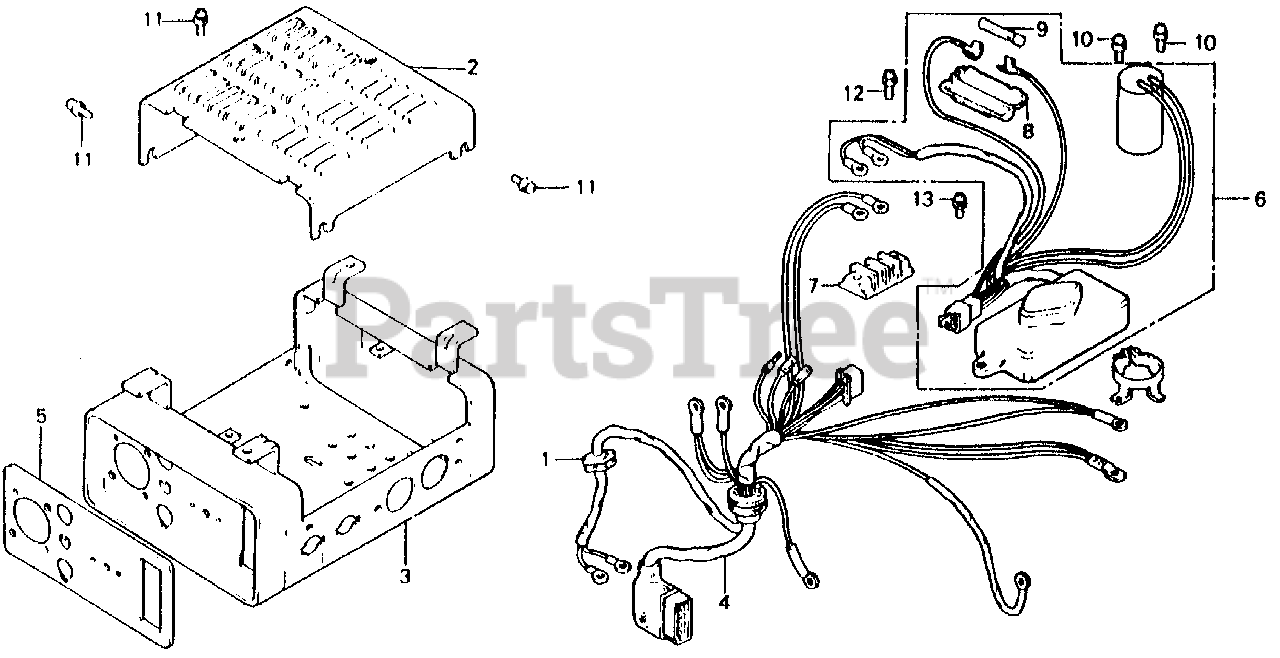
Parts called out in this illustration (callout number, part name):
1	BUSH, RUBBER
2	COVER, CONTROL BOX (UPPER) *R8* (BRIGHT RED)
3	COVER, CONTROL BOX (LOWER) *R8* (BRIGHT RED)
4	WIRE HARNESS ASSY. (NOT AVAILABLE)
5	PANEL, FR.
6	REGULATOR ASSY., AUTOMATIC VOLTAGE
7	TERMINAL (2 POLE)
8	CASE, FUSE CONNECTOR
9	FUSE (2.5A)
10	SCREW-WASHER (4X6)
10	SCREW-WASHER (4X10)
11	SCREW-WASHER (4X6)
11	SCREW-WASHER (4X10)
12	SCREW-WASHER (4X16)
13	SCREW-WASHER (5X16)
